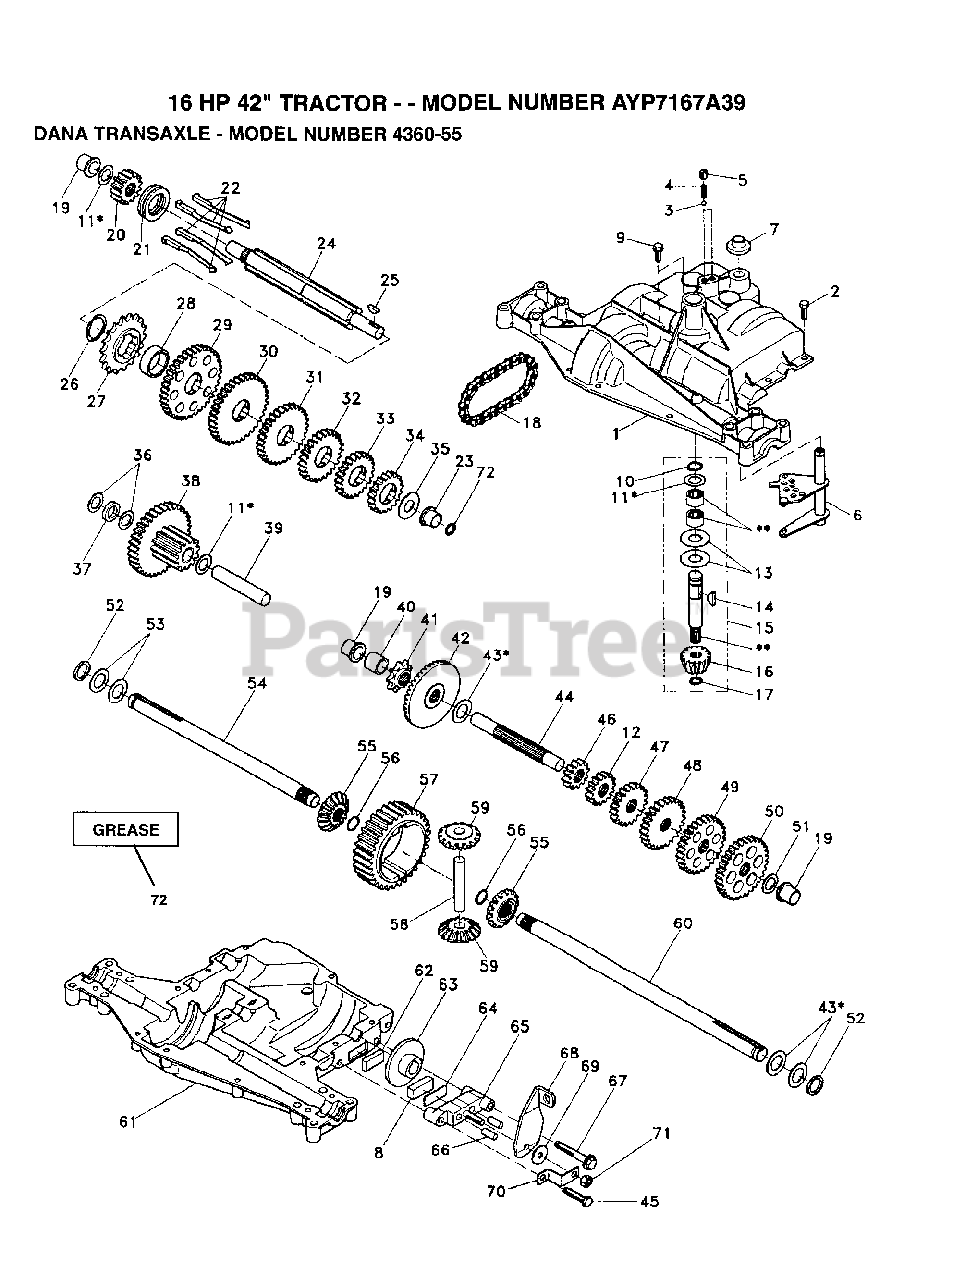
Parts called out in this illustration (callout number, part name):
1	HOUSING UPPER
3	BALL, DETENT
4	SPRING, DETENT
5	SCREW, SET
6	KIT, SHIFTER ASSEMBLY
7	BOOT, SHIFTER
8	PUCK, FRICTION
9	SCREW TAPPING WITH SEALER
10	RING RETAINING
11	ASSY, KIT, SHIM .625 SHAFT
12	GEAR SPUR, 15 TEETH
13	WASHER, PLAIN .632 X 1.38 X .046
14	KEY WOODRUFF #9
15	ASSY KIT INPUT SHAFT
16	PINION BEVEL 14 TEETH
17	RING, RETAINING
18	CHAIN, 24 PITCHES
19	BEARING, FLANGE
21	COLLAR, CLUTCH
22	ASSY KIT CLUTCH KEYS
23	BEARING FL
24	SHAFT INTERMEDIATE
25	KEY, WOODRUFF, #61
26	RING, RETAINING
27	SPROCKET, 18 TEETH
29	GEAR, SPUR, 37 TEETH
30	GEAR, SPUR, 35 TEETH
31	GEAR, SPUR, 30 TEETH
32	GEAR, SPUR, 25 TEETH
33	GEAR, SPUR, 22 TEETH
34	GEAR, SPUR, 19 TEETH
35	WASHER, PLAIN .640 X 1.37 X .061
36	WASHER, PLAIN .632 X 1.00 X .026
37	SPACER .630 X 1.00 X .169
38	ASSY GEAR COMB 12&35 TEETH
39	SHAFT, IDLER
40	SPACER .635 X .875 X .755
41	SPROCKET, 9 TEETH
42	GEAR, BEVEL, 42 TEETH
43	ASSY, KIT, SHIM .750 SHAFT
44	SHAFT, DRIVE
45	SCREW TAPPING
46	GEAR, SPUR, 12 TEETH
47	GEAR, SPUR, 20 TEETH
48	GEAR, SPUR, 25 TEETH
49	GEAR, SPUR, 28 TEETH
50	GEAR, SPUR, 31 TEETH
51	WASHER, PLAIN .632 X 1.00 X .060
52	WASHER, NEOPRENE
53	WASHER, PLAIN .758 X 1.25 X .031
54	AXLE LEFT HAND
55	GEAR MITER 15 TEETH
56	RING, RETAINING
57	GEAR, SPUR, 32 TEETH
58	SHAFT, CROSS
59	GEAR, MITER, 15 TEETH
60	AXLE, R.H.
61	HOUSING LOWER
62	PUCK, FRICTION
63	DISC, BRAKE
65	JAW, BRAKE
66	PIN, DOWEL
67	SCREW, SELF-TAPPING
68	LEVER ACTUATING
69	WASHER, PLAIN .321 X 1.00 X .055
70	BRACKET, ANTI-ROTATION
71	LOCKNUT 5/16-24
72	SQUARE RING
